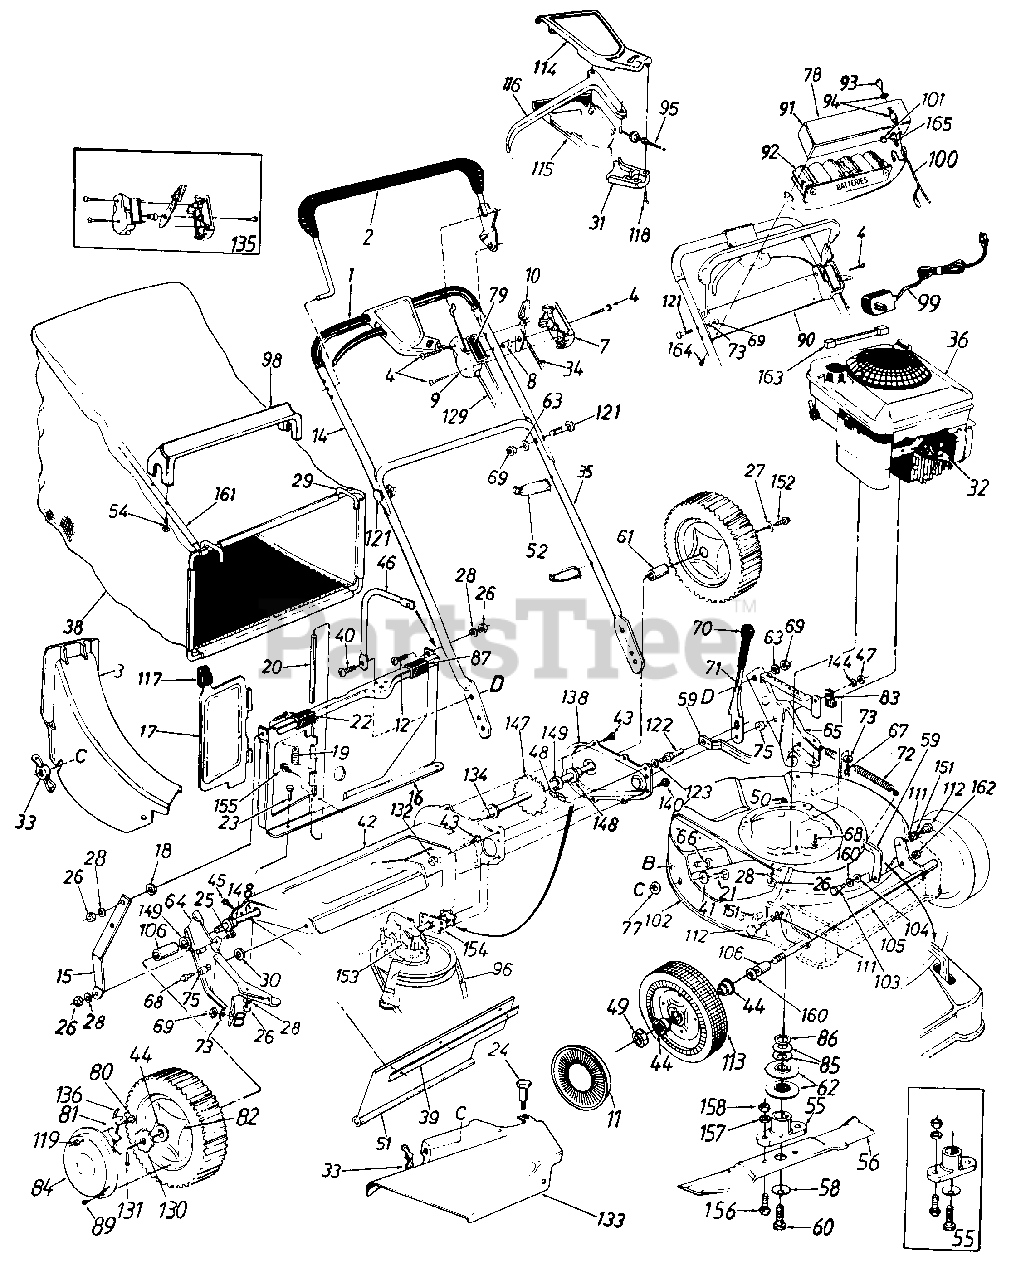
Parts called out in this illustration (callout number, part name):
1	Foam Grip
2	Control Handle Ass'y. w/Plastic
3	Rear Discharge Chute Ass'y.
4	Truss Mach. Scr. #12 x 1.50" Lg.
7	Control Panel Half
8	Control Disc Pin
9	Clutch Panel Half
10	Throttle Control Lever
11	Hub Cap (Black)
12	Truss Mach. Scr. 1/4-20 x .62"
15	Panel Support Brkt.
19	Torsion Spring
20	Pivot Pin
21	Carriage Bolt 1/4-20 x .62"
22	Truss Mach. Scr. 1/4-20 x 3/4" Lg.
23	Hex Bolt 1/4-20 x .50" Lg.
24	Shoulder Bolt .312 Dia. x .18 Lg.-Special
25	Hex Bolt 1/4-20 x .62" Lg.
26	Hex Nut 1/4-20 Thd. *
27	Bell-Wash. 1/4" I.D.
28	L-Wash. 1/4" I.D.
30	Fl-Wash. 3/8" I.D. x 1" O.D.
31	S.P. Control Cover
32	Spark Plug Insulator
33	Wing Nut w/Washer
34	Throttle Control Wire 58"
35	Lower Handle
36	Engine
38	21" Top Discharge Grass Bag- Black
39	Retaining Strip
40	Truss Mach. Scr. 5/16-18 x .75"
41	Fl-Wash. .344" I.D. x .62"
44	Flange Ball Bearing 1/2" I.D.
45	Hex AB-Tap Scr. 1/4 x .62"
46	Catcher Panel Support Arm
47	Hex Patch L-Nut 3/8-24 Thd.
48	#48 Chain .500n Pitch x 30 Links
49	Hex L-Nut 1/2-20 Thd.
51	Rear Flap 3.75" x l7.30" Lg.
52	Cable Tie
54	Hex AB-Tap Scr. #12 x 1.2"
55	Blade Adapter Kit
56	21" Blade
58	Bell-Wash. .46" I.D.
59	Height Adj. Connecting Arm
60	Hex Bolt 7/16-20 x 1.5" Lg. (Grade 5)
61	Spacer .513" I.D. x .703" O.D. x .69" Lg
62	Serrated Pulley Half
63	L-Wash. 5/16" I.D.
64	R.H. Handle Wheel Brkt. Ass'y.
65	L.H. Handle Wheel Brkt. Ass'y.
66	Carriage Bolt 5/16-18 x .62"
67	Hex Wash. Hd. B-Tap Scr. 5/16-18
68	Hex Wash. Hd. TT-Tap Scr. 3/8-16
69	Hex Nut 5/16-18 Thd.
71	Height Adj. Lever
72	Extension Spring .75" O.D. x 8" Lg.
73	Bell-Wash. 5/16" I.D.
75	Shld. Spacer .500" Dia.
77	Bolt Retainer 1/4 x .50" O.D.
78	Instruction Label
79	Control Label
80	Shld. Scr. .342" Dia. x .268
81	Pawl
82	Wheel Ass'y. Comp.
83	Clamp
84	Hub Cap
85	Bell-Washer 1.01" I.D.
86	Crankshaft Spacer
87	Panel Clip
89	Pan Hd. Tap Scr. #12
90	Lower Battery Tray
91	Upper Battery Tray
92	12 Volt Battery
93	Key
94	Key Switch
95	S.P. Cable x 43" Lg.
96	"V"-Belt
98	Bag Handle (Black)
99	Battery Charger
100	Wire Harness
101	Plug
102	21" Deck Ass'y.
103	Shld. Bolt .5" Dia. x .295
104	Bell-Wash. .515" I.D. x 1.0"
105	Front Axle Ass'y.
106	Sleeve .526" I.D. x.690" O.D. x.880" Lg.
111	Intern. L-Wash. 3/8 I.D.
112	Shld. Bolt .575" Dia. x .42
113	Wheel Ass'y. Comp.
114	Self-Propelled Control Cover
115	Self-Propelled Control Cover
116	Control Lever
117	Door Grip
118	Fl-"C"-Sunk Hd. Tap Scr. #10 x .75" Lg.
119	Hex Ins. L-Nut 1/4-20 Thd.
121	Curved Carr. Bolt 5/16-18 x 1.38" Lg.
122	Shld. Pin 3/8-24 x 1.43" Lg.
123	L-Wash. 3/8" I.D.
129	Control Cable 46" Lg.
130	Ratchet Wheel 1.62" O.D.
131	Cotter Pin 1/8" Dia. x 1.00" Lg.*
132	Hex Jam Nut 3/8-24 Thd.
133	Side Chute Deflector Ass'y.
134	Hex Flange Bearing
135	Kit-Control Housing Comp.
136	Spring-Nylon
144	Fl-Wash. .885" I.D. x .37"
147	Rear Shaft Ass'y. 21.94" Lg.
148	Hex Flange Bearing .506" I.D. Plastic
149	Fl-Wash. .531" I.D. x .930"
151	Flanged Nyliner Brg.
152	Hex Bolt 1/4-20 x .62" Lg. (Grade 5)
153	Transmission Comp.
155	Hex B-Tap Scr. #10 x .38
156	Hex Bolt
157	L-Wash. 3/8" I.D.
158	Hex Nut 3/8-24 Thd.
160	Fl-Wash. .51" I.D. x .75" O.D.
162	Hex Jam Nut 3/8-18 Thd.
163	Extension Harness
164	Truss Mach. Tap Scr. 1" Lg.
165	Fuse Holder
